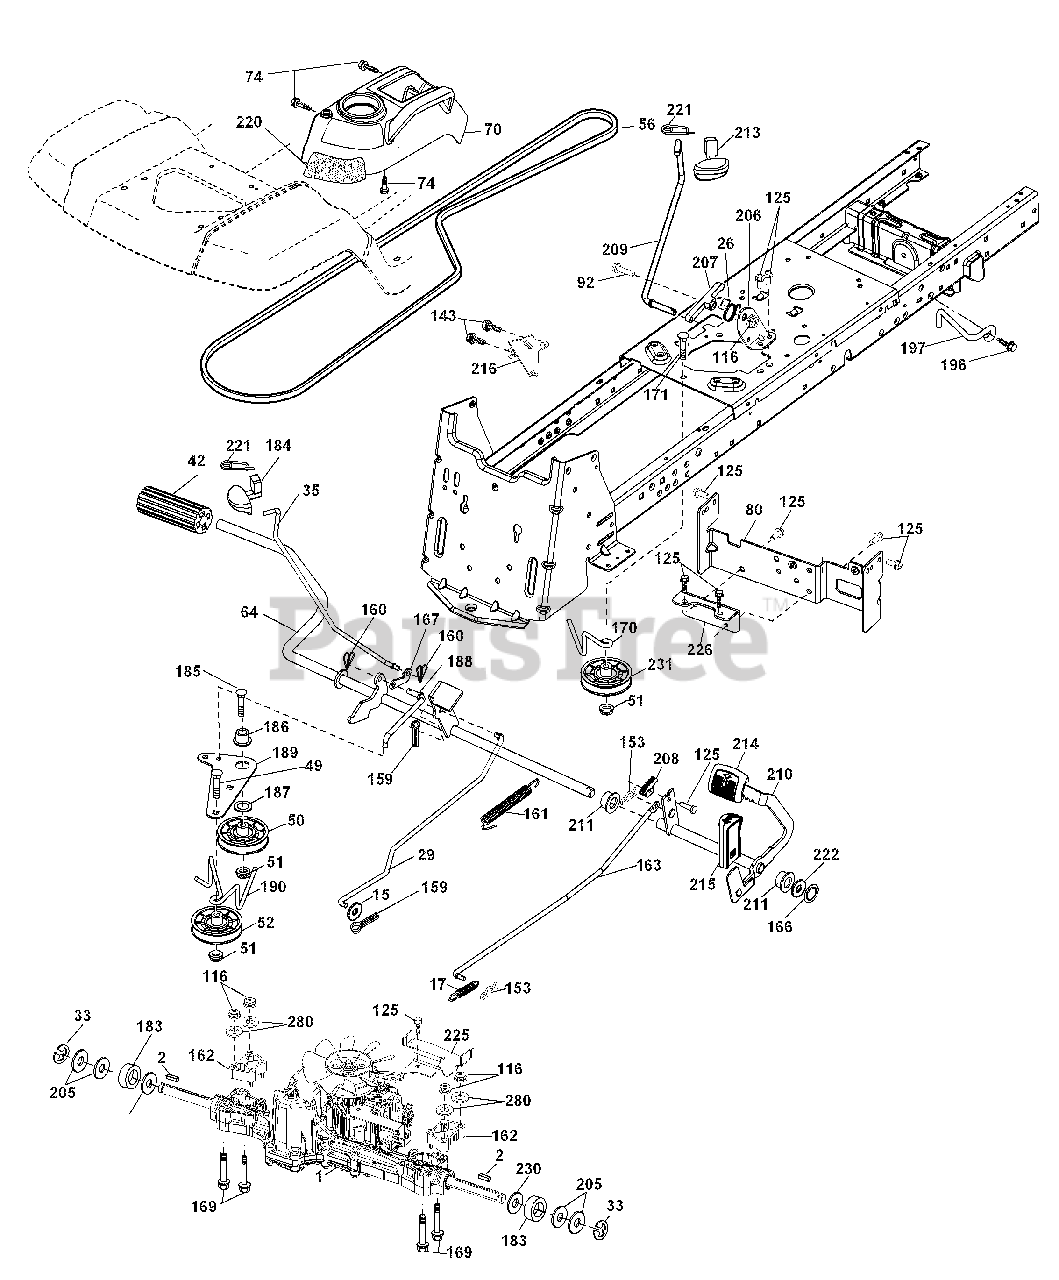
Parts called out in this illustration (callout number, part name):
1	Transaxle, TUFFTORQ K46
7	Hub Asm. Wheel
9	Bolt Hub Wheel
15	Washer 13/32 x 13/16 x 16 Ga.
17	Spring, Brake
26	Spring Return Cruise
29	Rod, Brake
35	Rod, Brake, Park
42	Cover, Foot Pedal
50	Pulley Idler Flat
51	Lock Nut 3/8-16
52	Idler V-Groove 910" Offset
56	V-Belt, Drive
64	Shaft Asm. Pedal Brake Control
70	Console Asm.
74	Screw 1/4 x 1/2
80	Strap Torque
92	Bolt Fin Hex 5/16-18 unc x 1.25
116	Nut Lock Hex Flange 5/16-18
125	Screw 5/16-18 x 3/4
143	Screw Thdrol 5/16-18 x 1/2
153	Retainer Spring
159	Pin Cotter 1/8 x 3/4
160	Retainer Clip
161	Spring, Return, Clutch
162	Spacer Transaxle
163	Rod Pedal Control
166	Nut Push .625
167	Latch Brake Parking
169	Bolt 5/16-18 x 4.5 Gr. 5
170	Keeper Belt Centerspan
171	Bolt 3/8 - 16 x 2-3/4 Gr. 5
183	Spacer Split
184	Handle Parking Brake
185	Bolt Rdhd Sqnk 3/8-16 x 2-1/2
186	Spacer Retainer
187	Washer
188	Link Clutch Ground Drive
189	Bellcrank Ground Drive
190	Keeper Bellcrank Ground Drive
196	Screw 3/8-16 x 1
197	Bracket Clutch Anti-Rotation
206	Bracket Mount Latch Cruise
207	Latch Control Cruise
208	Gear Sector Control Cruise
209	Rod Control Cruise
210	Rocker Asm. Pedal Control
211	Bearing Nylon
213	Knob Control Cruise
214	Pedal Forward
215	Pedal Reverse
216	Bracket Pulley Idler
220	Reflector RH
221	Retainer Spring Clip Handle
222	Washer 21/32 x 1-1/4 x 10 Ga.
225	Keeper Belt Trans.
226	Bracket Mount Touque
231	Idler V-Groove Pulley
280	Washer 11/32 x 5/8 x 12 Ga.
